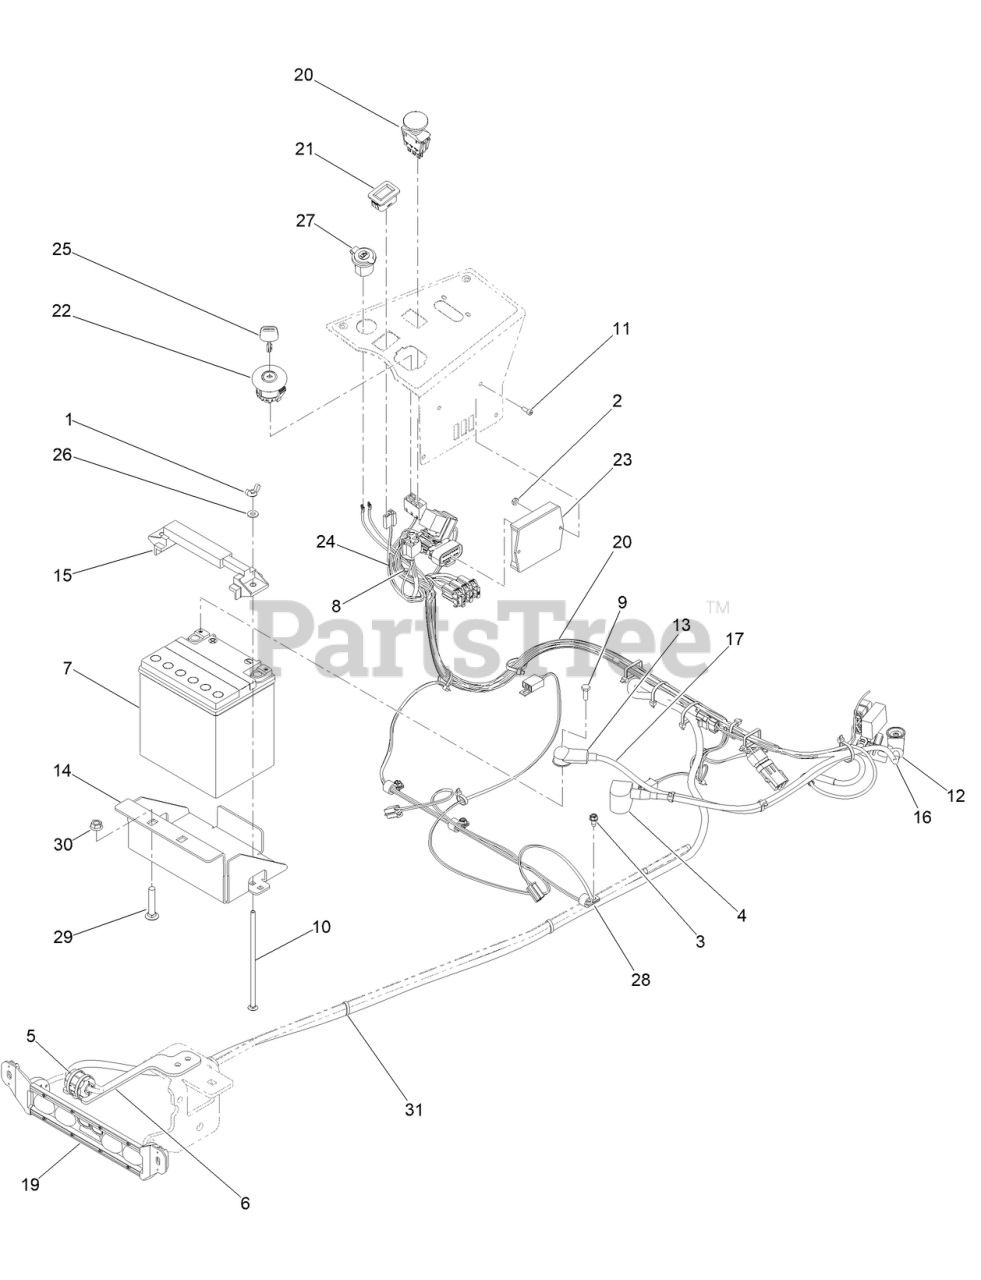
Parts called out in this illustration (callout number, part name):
1	NUT-WING
2	NUT-LOCK
3	SCREW-HWH
4	INSULATOR-BATTERY
5	FAIR-RITE ROUND CABLE SNAP-IT SIZE B
6	FAIR-RITE BRACKET PAINTED
7	BATTERY - ETX30LA - 400CCA
8	6IN (40 LB) CABLE TIE NYLON UV
9	SCREW-HH
10	1/4-20 X 7 CARRIAGE BOLT ZINC
11	10-24 X 1/2 SOCKET C/S 18-8 SS
12	3.15 LGTH STRAIGHT INSUL TERM COVER RED
13	STRAIGHT INSULATING TERMINAL COVER
14	MWR BATTERY BOX
15	BATTERY HOLD DOWN
16	MWR POSITIVE BATTERY CABLE 25IN
17	MWR NEGATIVE CABLE 28
19	FULL BEAM WITH LIGHTED HELMET LIGHT BAR
20	PTO SWITCH
21	HOUR METER
22	IGNITION SWITCH
23	INTERLOCK MODULE
24	MWR KEYSWITCH JUMPER HARNESS
25	2023 MWR KEY
26	WASHER-FLAT
27	12 VOLT AUXILLIARY PLUG
28	CLAMP-R
29	SCREW-CARR
30	3/8-16 HEX FLANGE NUT W/SERR ZINC YELLOW
31	TIE-CABLE
